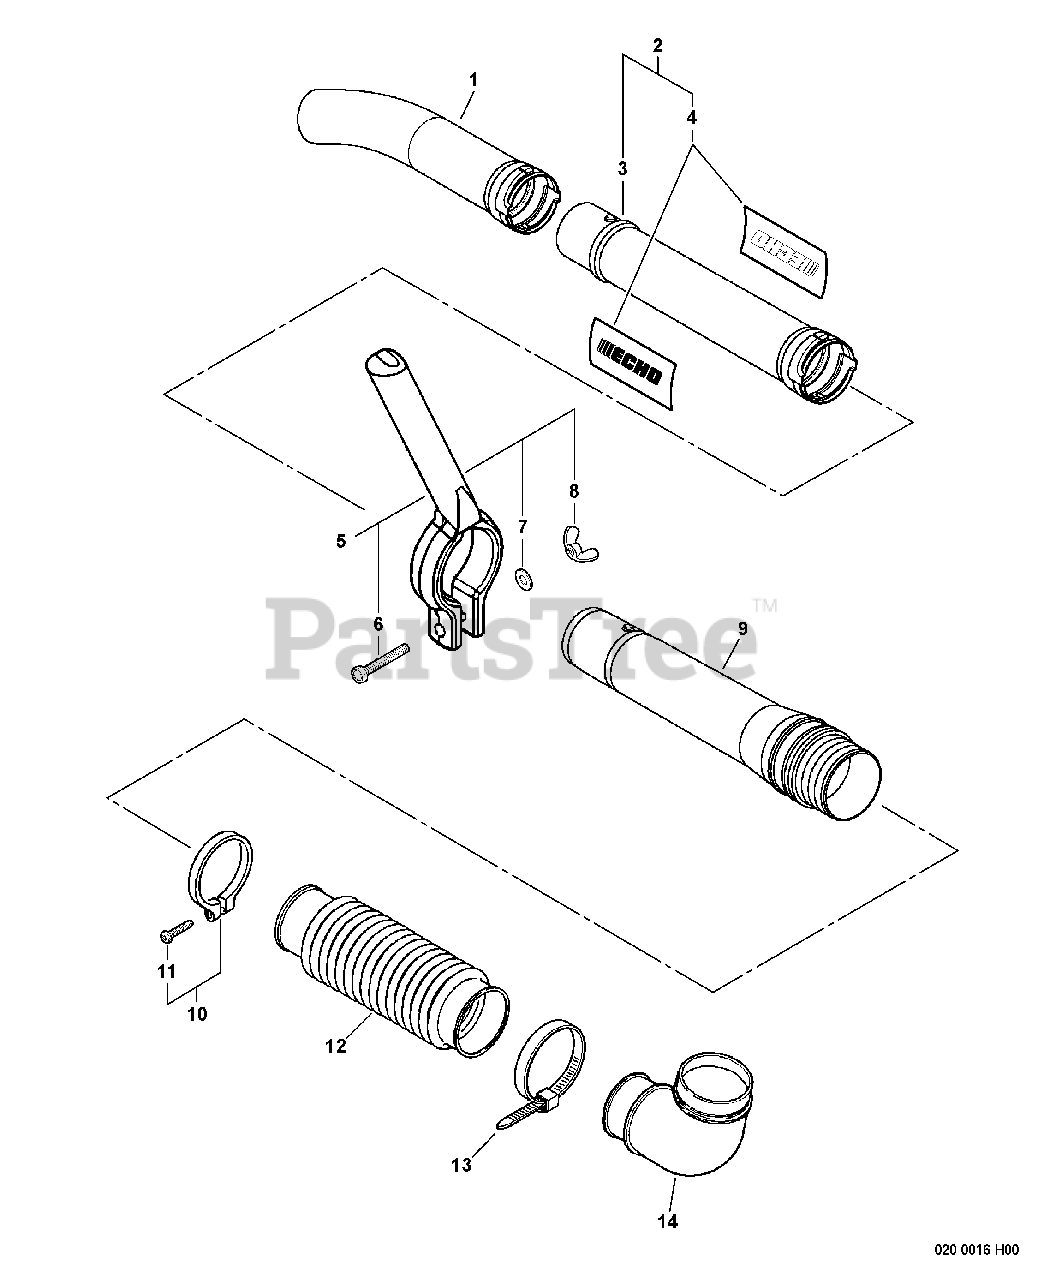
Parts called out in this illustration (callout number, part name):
1	TUBE, BLOWER - CURVED
2	BLOWER TUBE KIT - STRAIGHT
3	TUBE, BLOWER - STRAIGHT
4	LABEL, ECHO BLOWER TUBE
5	HANDLE ASSY
6	BOLT 6×45
7	WASHER 6.5×11.5×0.8
8	NUT, WING 6
9	TUBE, BLOWER - SWIVEL
10	CLAMP KIT
11	SCREW 5×30
12	TUBE, FLEXIBLE
13	CLAMP 58.7 MM / 82.5 MM
